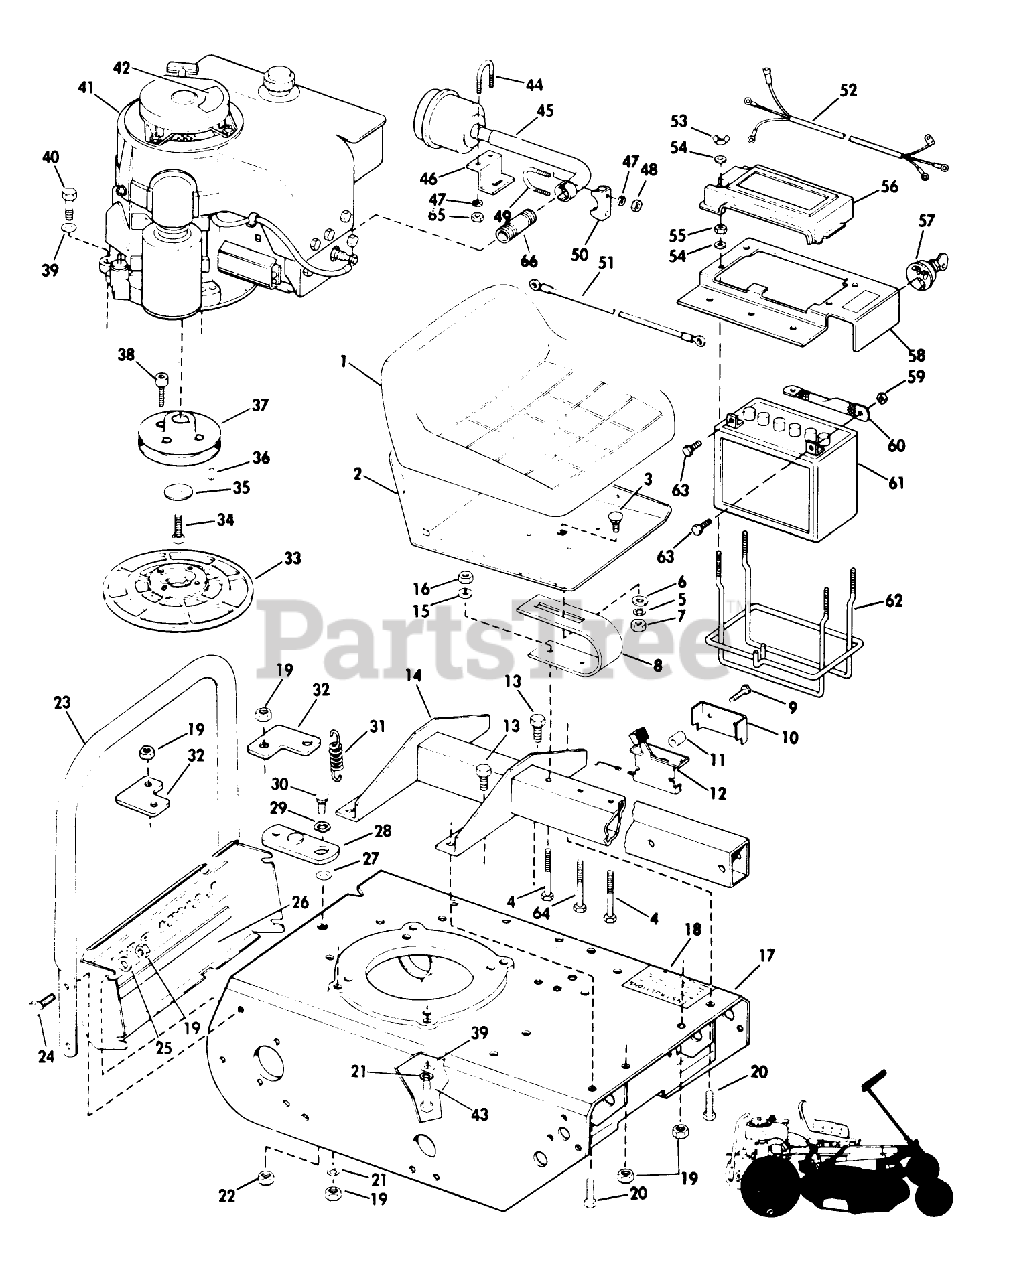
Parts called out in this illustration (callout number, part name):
12	Throttle Control Assembly
42	Decal-Caution
49	U Bolt, Muffler
55	STOP NUT
